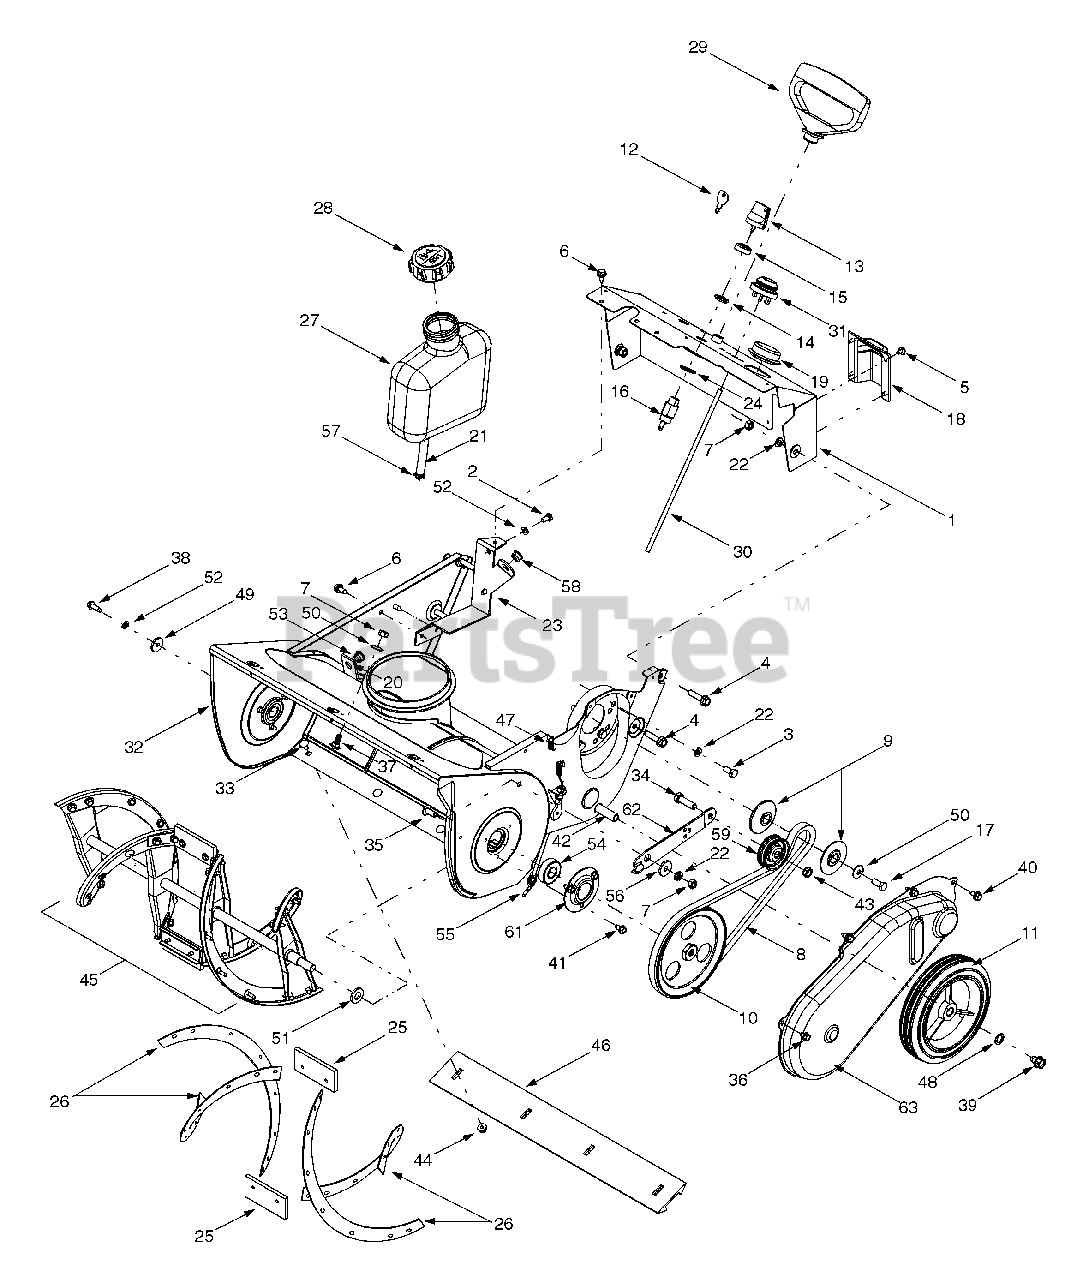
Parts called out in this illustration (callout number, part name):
3	Hex Cap Screw, 5/16-24 x .625
4	Hex Flange Screw, 5/16-18 x 1.25
5	Screw, #10-16 x .375
6	Self-tapping Screw, 1/4-20 x .625
7	Hex Nut, 5/16-18
8	Drive Belt
9	Pulley Half-.625 x 2.25
10	Auger Drive Pulley
11	Wheel Assembly, 7 x 1.5
12	Ignition Key
13	Ignition Key w/ Plastic Cover
14	Ignition Nut, 5/8-32
15	Ignition Switch Cap
16	Ignition Switch
17	Hex Cap Screw, 5/16-24 x .75
18	Choke Cover
19	Spark Plug Cap
22	Lock Washer, 5/16
25	Rubber Paddle
26	Rubber Paddle/Spiral
27	Gas Tank, 2 qt.
28	Fuel Cap (50:1 Red Print)
29	Recoil Handle (Mitten Grip)
30	Primer Tube
31	Primer Bulb
34	Cap Screw, 3/8-24 x 1.25
35	Trus Machine Screw, 5/16-18 x .75
36	Hex Index Washer Screw, 1/4-14 x .375
37	Carriage Bolt, 5/16-18 x .75
38	Self-tapping Screw 1/4-20 x .75
39	Self-tapping Screw 3/8-16 x .50
40	Self-tapping Screw, 1/4-14 x .625
41	Self-tapping Screw, 1/4-14 x .50
42	Axle, .35 x .5 x 20.75
43	Jam Lock Nut, 3/8-24
44	Hex Flange Lock Nut, 1/4-20
46	Shave Plate, 2.66 x 19.88
47	Extension Spring, .33 x 1.12
48	Flat Washer, .51 x .75 x .033
49	Flat Washer, .265 x .938 x .120
50	Belleville Washer, .340 x .872
51	Flat Washer, .51 x 1.0 x .125
52	Lock Washer, 1/4
53	Plastic Bushing
54	Ball Bearing, 17mm x 40mm x 12mm
55	Cable, 41.78"
56	Shoulder Spacer
57	Hose Clamp, .49
58	Plastic Bushing, .38
59	Flat Idler Pulley, 1.88 x .50 x 2.12
